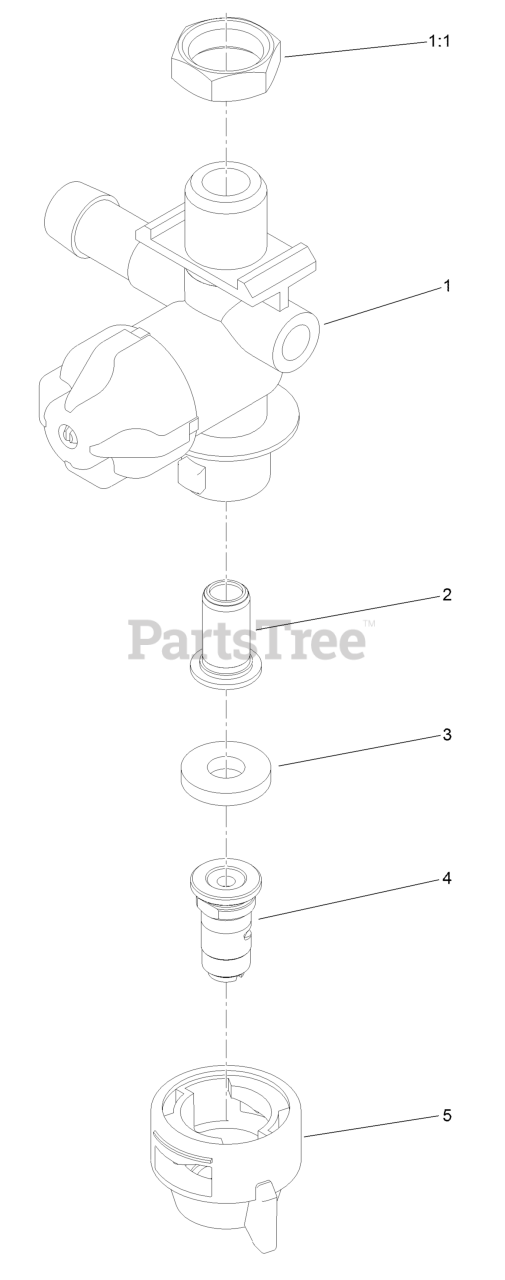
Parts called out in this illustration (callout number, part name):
1	RH NOZZLE BODY ASM
1:1	NUT-NYLON
2	STRAINER-TIP
4	NOZZLE-SPRAY, WHITE
5	CAP-NOZZLE
